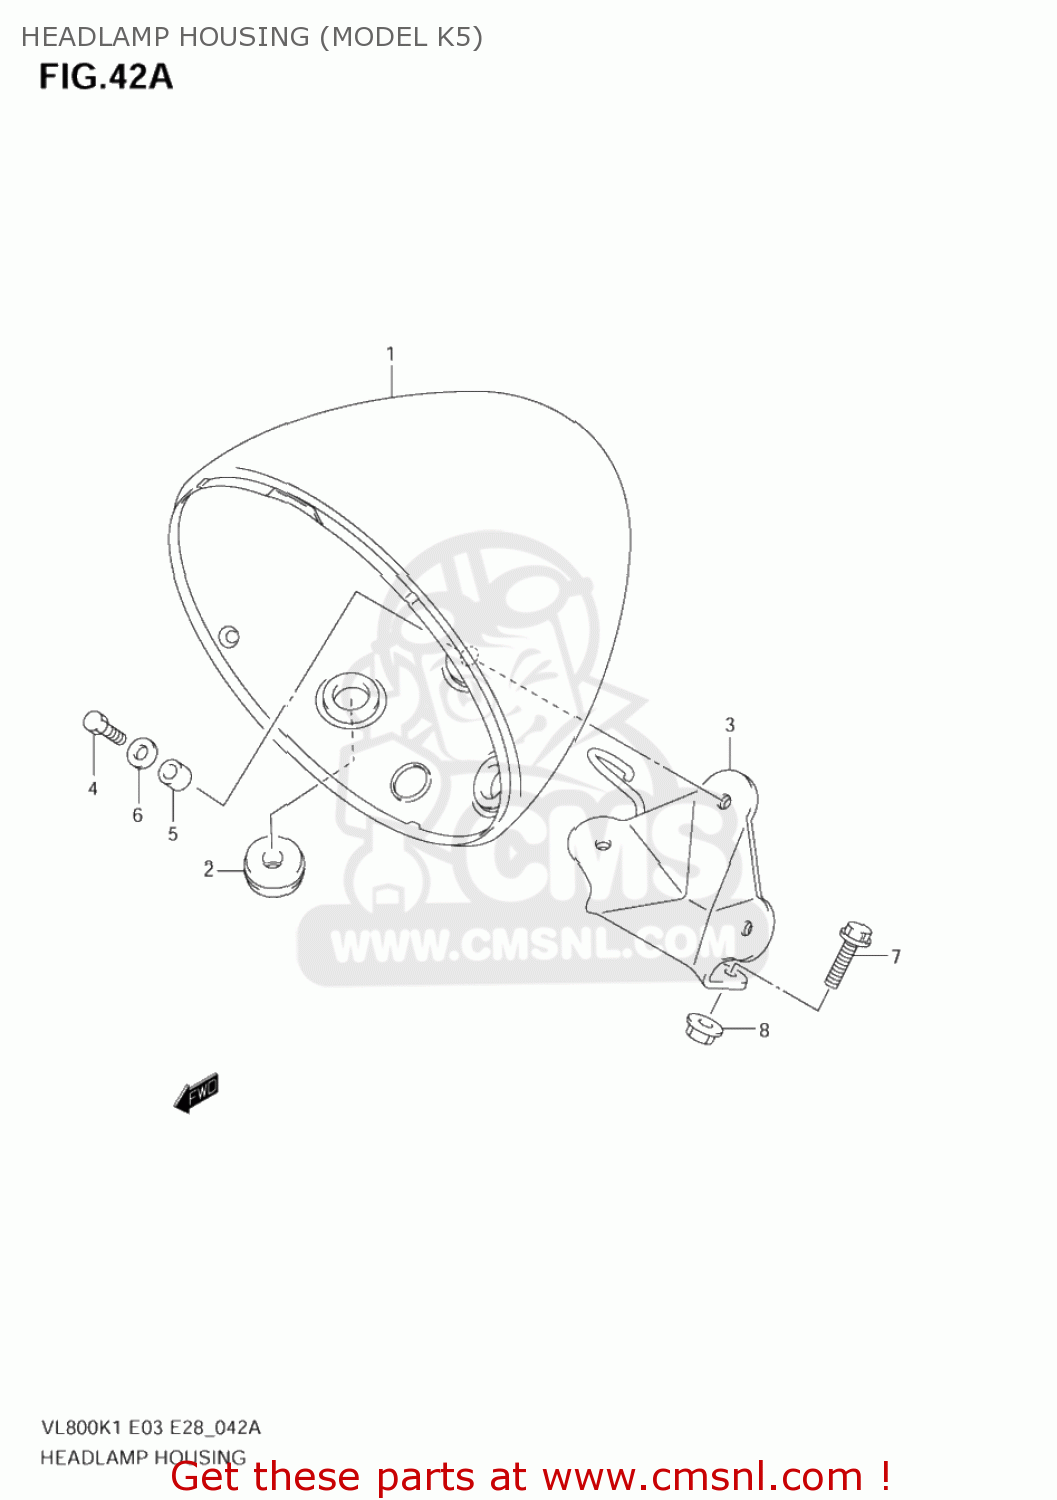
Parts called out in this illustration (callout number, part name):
1	HOUSING ASSY,HEADLAMP
2	CUSHION
3	BRACKET,HEADLAMP HOUSING
4	BOLT
5	SPACER(6.5X9X10)
6	WASHER(6.5X20X1.2)
7	BOLT
8	NUT
